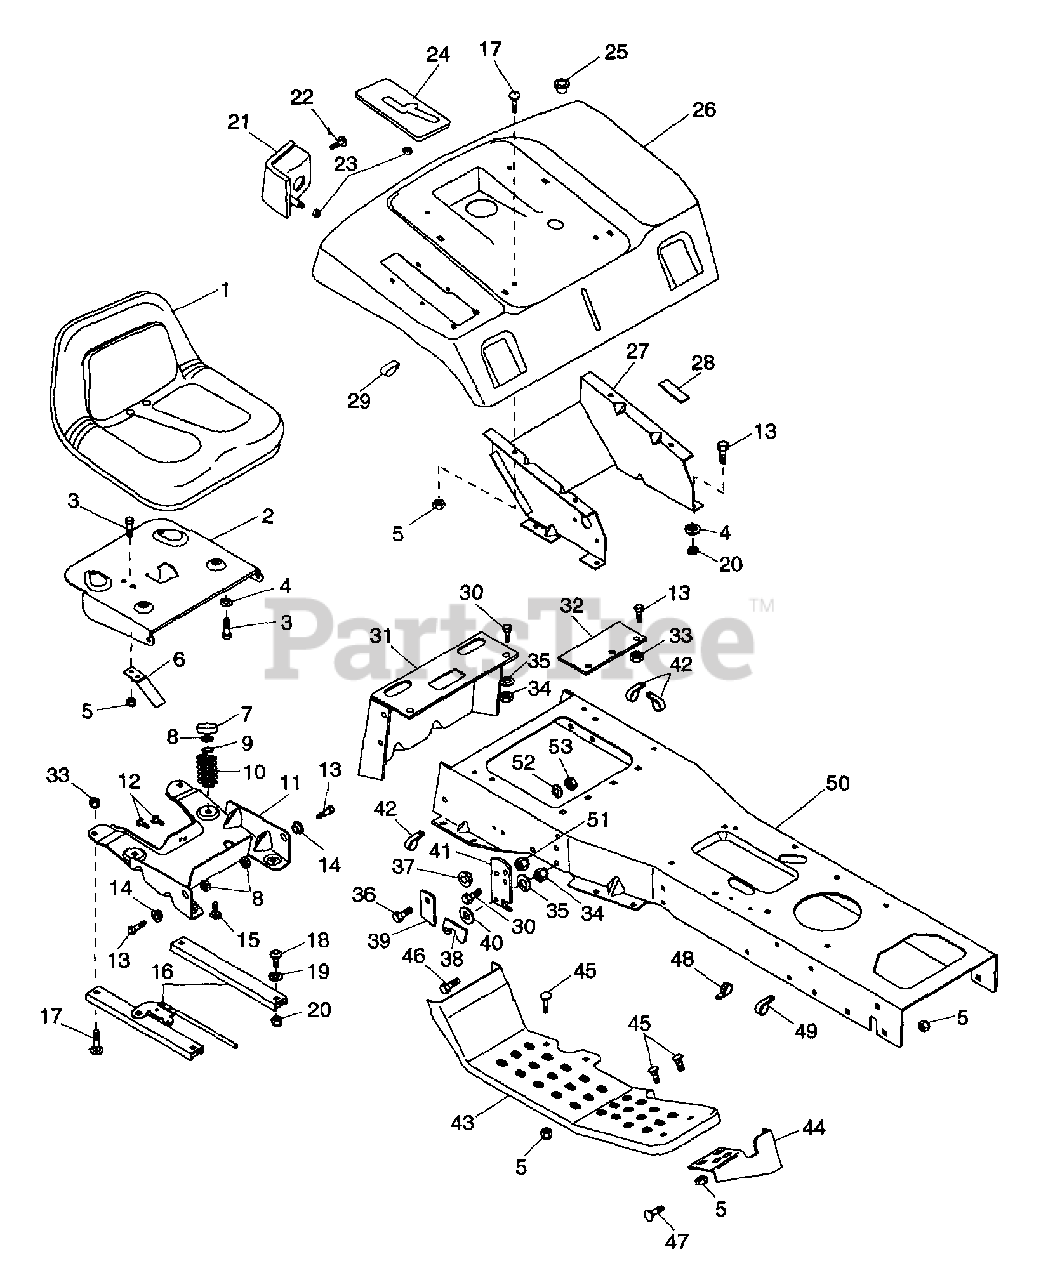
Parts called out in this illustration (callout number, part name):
1	SEAT- V-560
2	SEAT PIVOT PLATE
3	BLT-HEX .31-18X.75 PL GR2
4	WSHR-LK .312X.097 PL HVY
5	NUT-FLG. .312-18 PL
6	SPRING PLATE
7	TUBE CAP
8	NUT-LK .312-18 GR A PL
9	WSHR-FL-STL.344X.688X.065PL
10	SG-COMP .148X1.23X2.41 WLD87
11	BOX, SEAT
12	SCR-TAP 12-24X.50 HWH PL TR
13	BLT-HEX .31-18X.75 PL GR5
14	BSHG-FLG .325X.465X.333X.685
15	BLT-RDHDSQNK.31-18X.75GR5SHTPL
16	SEAT SLIDES -(RAME TAK-3010-4)
17	BLT-RDHDSQNK .312-18X.62SHTPL
18	SCR-CAP BTHD.31-18X.50 GR5 YZ
19	WSHR-LK-EXT .313X.030 PL
20	NUT-HEX .312-18
21	RIGHT TAIL LIGHT
21	LEFT TAIL LIGHT
22	SCR-TAP 10-12X.50 CRPH PL A
23	NUT-SELF-THRDNG FITS.25 STUDPL
25	GROMMET 1.0ID X 1.38 OD
26	REAR DECK F/TL
26	REAR DECK- HYDRO
27	DECK SUPPORT
28	FOAM TAPE
29	WIRE CLIP
30	BLT-HEX .38-16X1.00 PL GR5
31	TAILBOARD
32	SUPPORT PLATE
33	NUT-LK-NYL.312-18 PL
34	NUT-HEX .375-16
35	WSHR-LK .375X.115 HVY PL
36	BLT-HEX .38-16X1.50 PL GR5
37	SPACER .400X.625X.400X.875
38	LATCH RH
38	LATCH LH
39	LOCK STOP
40	SPRING WASHER
41	REAR HANGER
42	J-CLAMP
43	FOOTREST RH
43	FOOTREST LH
44	R. FOOT REST BRACE
44	L. FOOT REST BRACE
45	BLT-RDHDSQNK .31-18X.75 GR5 PL
46	BLT-HEX .25-20X.63 PL GR2
47	BLT-RDHDSQNK .31-18X.75 SHT PL
49	J-CLAMP
50	MAIN FRAME
51	NUT-LK TOP .375-16 GR C YWZC
52	WSHR-LK .250X.077 HVY PL
53	NUT-HEX .250-20 PL
